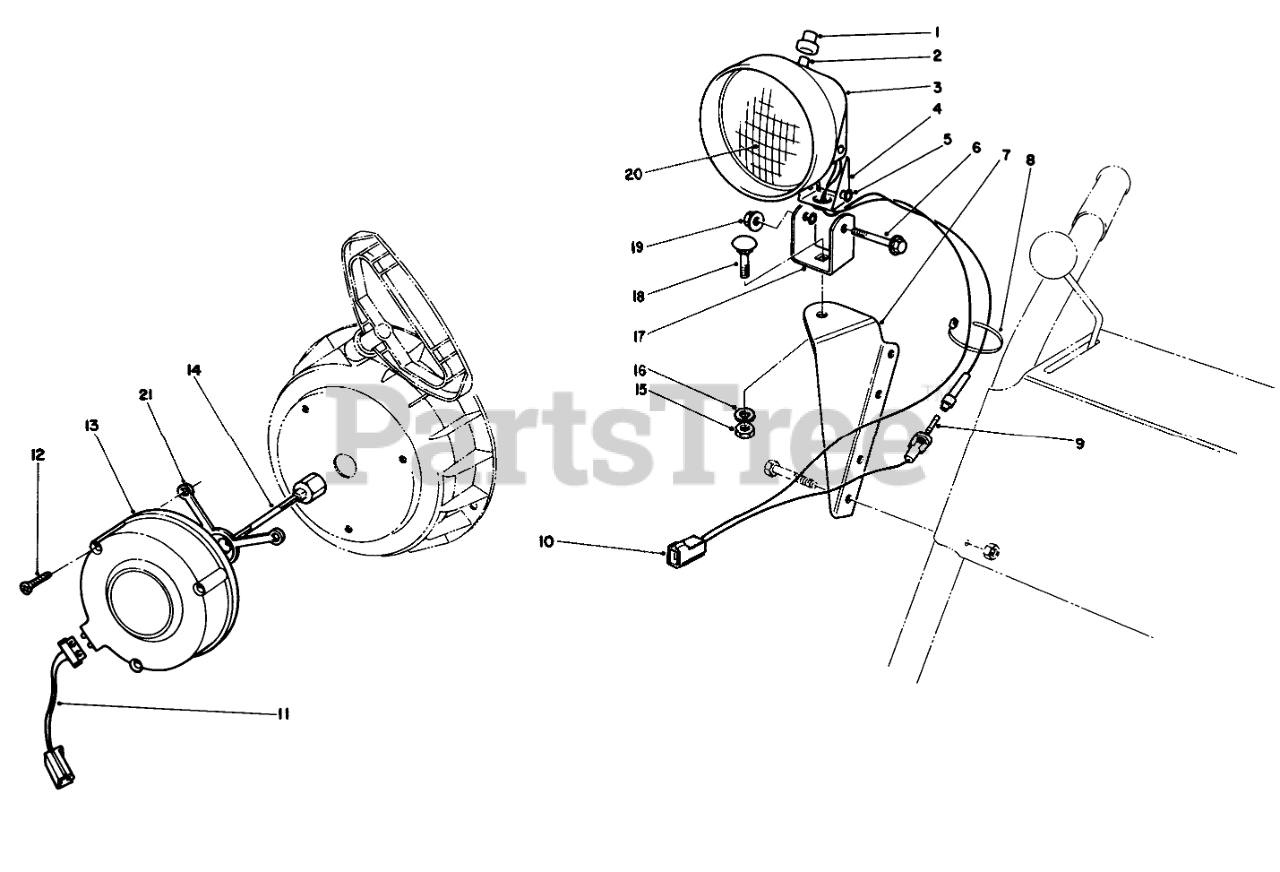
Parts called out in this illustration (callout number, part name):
1	BOOT-SWITCH
2	SWITCH ASM
3	Bucket-Headlamp
4	TO BE DISCONTINED-NOT NEEDED ON PRODUCT
5	WASHER-LOCK
6	SCREW-HH
7	LAMP MOUNT B
8	TIE-CABLE
9	Fuse-7-1/2 Amp.
10	WIRE ASM
11	Connector-Wire
12	SELF TAPPING SCREW
13	Alternator
14	Shaft-Alternator, 3 Inch
15	NUT-HEX
16	WASHER-LOCK
17	BRACKET
18	BOLT-CARR
19	NUT-HF
20	BEAM-SEALED
21	SPACER
